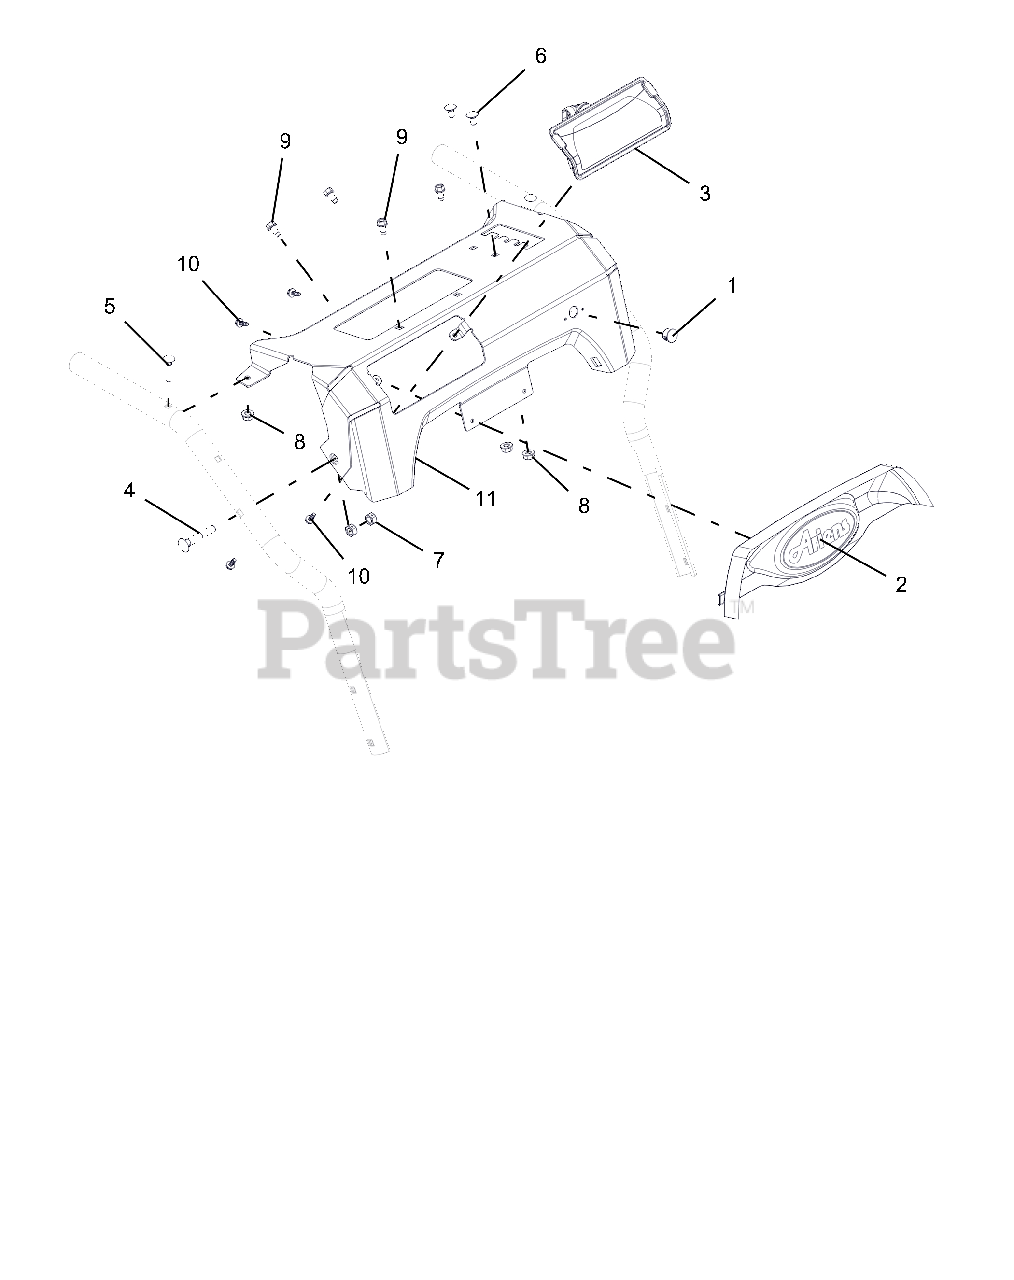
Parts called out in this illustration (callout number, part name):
1	HOLE PLUG, PLASTIC .56 HOLE
2	DASH BEZEL, ARIENS LOGO - COMP
3	HEADLIGHT ASY, HALO 20W 2SHOT
4	BLT-RDHDXLSQNK .31-18X2.0 G5YZ
5	BLT-RDHDXLSQNK.25-20X1.25 G5ZC
6	@BLT-RDHDSQNK .25-20X.50 G5YZ
7	@NUT-LK-CTR .31-18 YWZC
8	@NUT-LK-TOP-FLG .25-20 YWZC
9	SCR-TAP .25-20X.50 HWH TR YWZ
10	SCR-TAP #10X.50 BOSS INDHXHD
11	CONTROL PANEL W/DECAL, ARIENS
